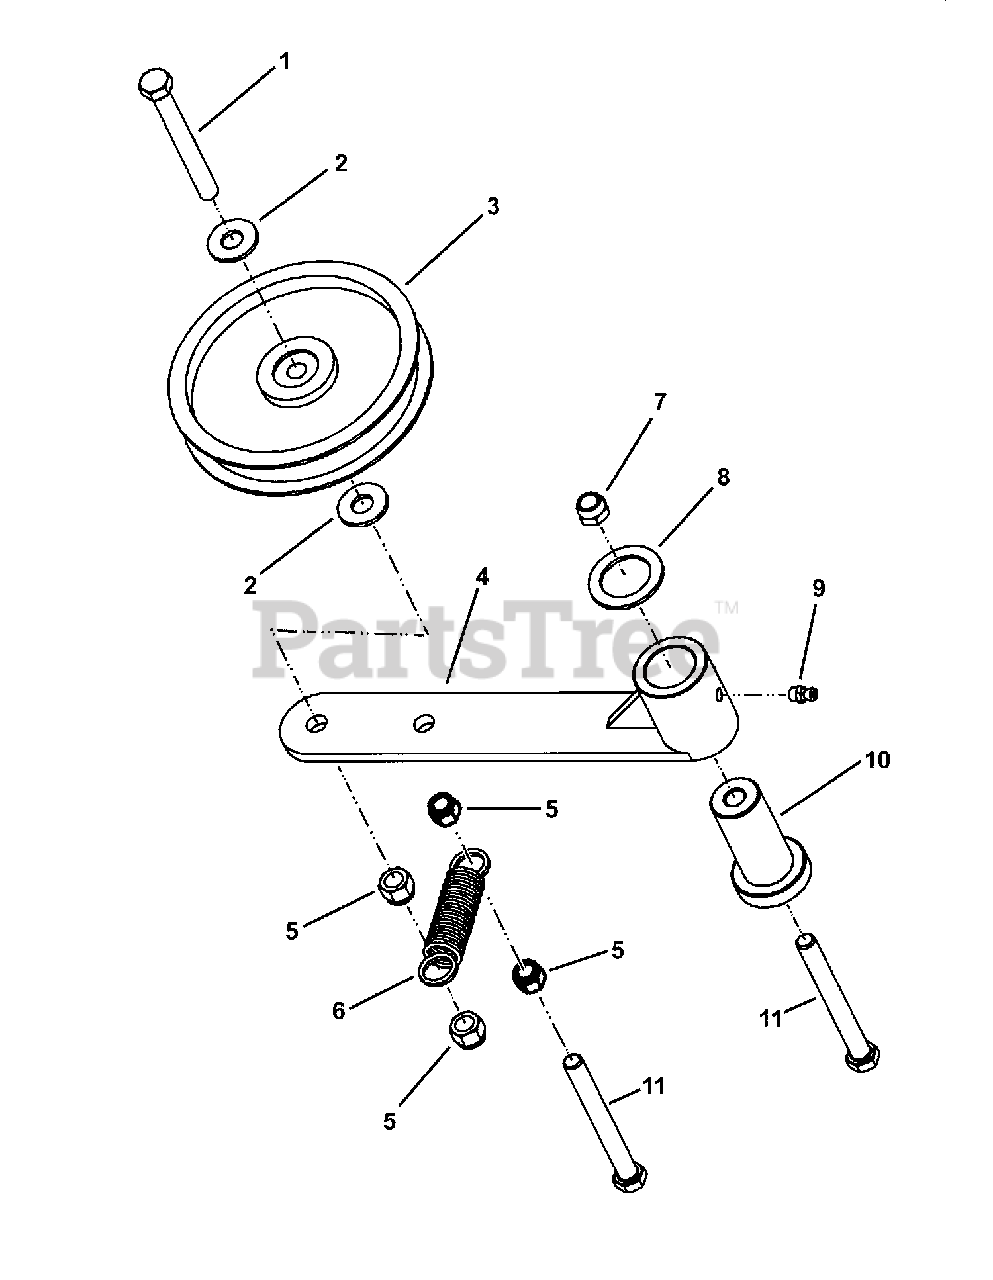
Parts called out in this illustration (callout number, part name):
1	BOLT, 3/8-16 x 3-1/4" Hex Head, GR 5
2	WASHER, 3/8" USS
3	PULLEY, Idler
4	IDLER ARM Weldment
5	NUT, 3/8-16 HEX NYLON LOCK
6	SPRING, Idler Tension (extension)
7	NUT, 3/8-16, HEX TOP LOCK
8	BUSHING, 1" x 14 Ga Machine
9	GREASE FITTING, 1/4-28 Straight
10	SPACER, Pivot
11	BOLT, 3/8-16 x 3-1/2" Hex Head, GR 5
